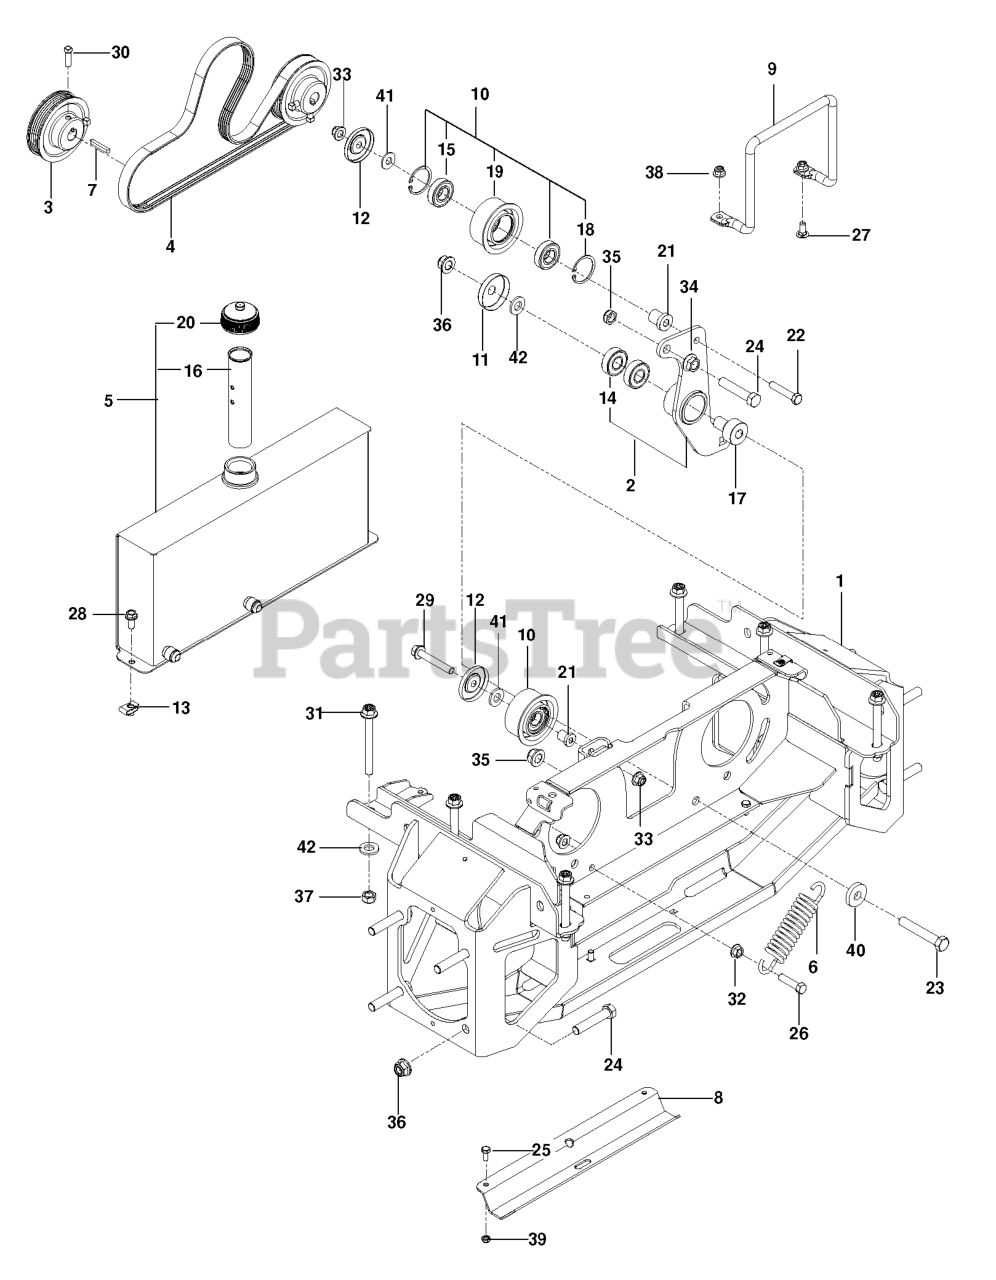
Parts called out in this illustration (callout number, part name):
1	WELDMENT, PUMP BAY, BLK
2	ASSEMBLY.IDLER.W/BEARINGS
3	PUMP SHEAVE
4	BELT, PUMP
5	ASSEMBLY, RESERVOIR
7	KEY, METRIC
8	GUARD, HOSE
9	GUIDE, BELT
10	IDLER, W/BEARINGS
11	SHIELD, DUST
12	DUST SHIELD
13	U-CLIP 5/16-18 NUT RETAINER
14	BEARING, BALL
16	TUBE, ANTI-SPLASH
17	PIVOT, BEARING
18	RING, RETAINING, 1-5/8"
19	IDLER, PUMP
20	CAP, HYDRAULIC
21	SPACER, IDLER
22	HCS 3/8C X 2
23	SCREW, 1/2C X 3 HEX CAP
24	HEX SCREW 1/2-13 X 2.5" GR 5
25	HCS 1/4C X 5/8
26	HCS 3/8-16 X 1-1/2
27	BOLT 5/16C X 3/4" CARRIAGE
28	HHFS 5/16-18 X 3/4
29	HHFS 3/8-16 X 2 3/4
30	SCREW 5/16C X 1 SQ HEAD SET
31	BOLT 7/16 X 4 GR 8 BLK PHOS
32	NUT 3/8C WHIZ
33	NUT 3/8-16 HEX FLG NYLOC ZD
34	NUT 1/2-13 HEX
35	NUT, HEX 1/2-13 THIN W/NY
36	NUT, 1/2-13 HEX FLG NYLOC ZD
37	7/16-14 HEX NUT W/NYL RING ZD
38	5/16-18 NYLOC FLANGE NUT
39	JAM NUT 1/4C (2 2 PW01)
40	WASHER .525 X 1.375 X .25
41	WASHER 3/8 FLAT
42	WASHER 1/2" FLAT
